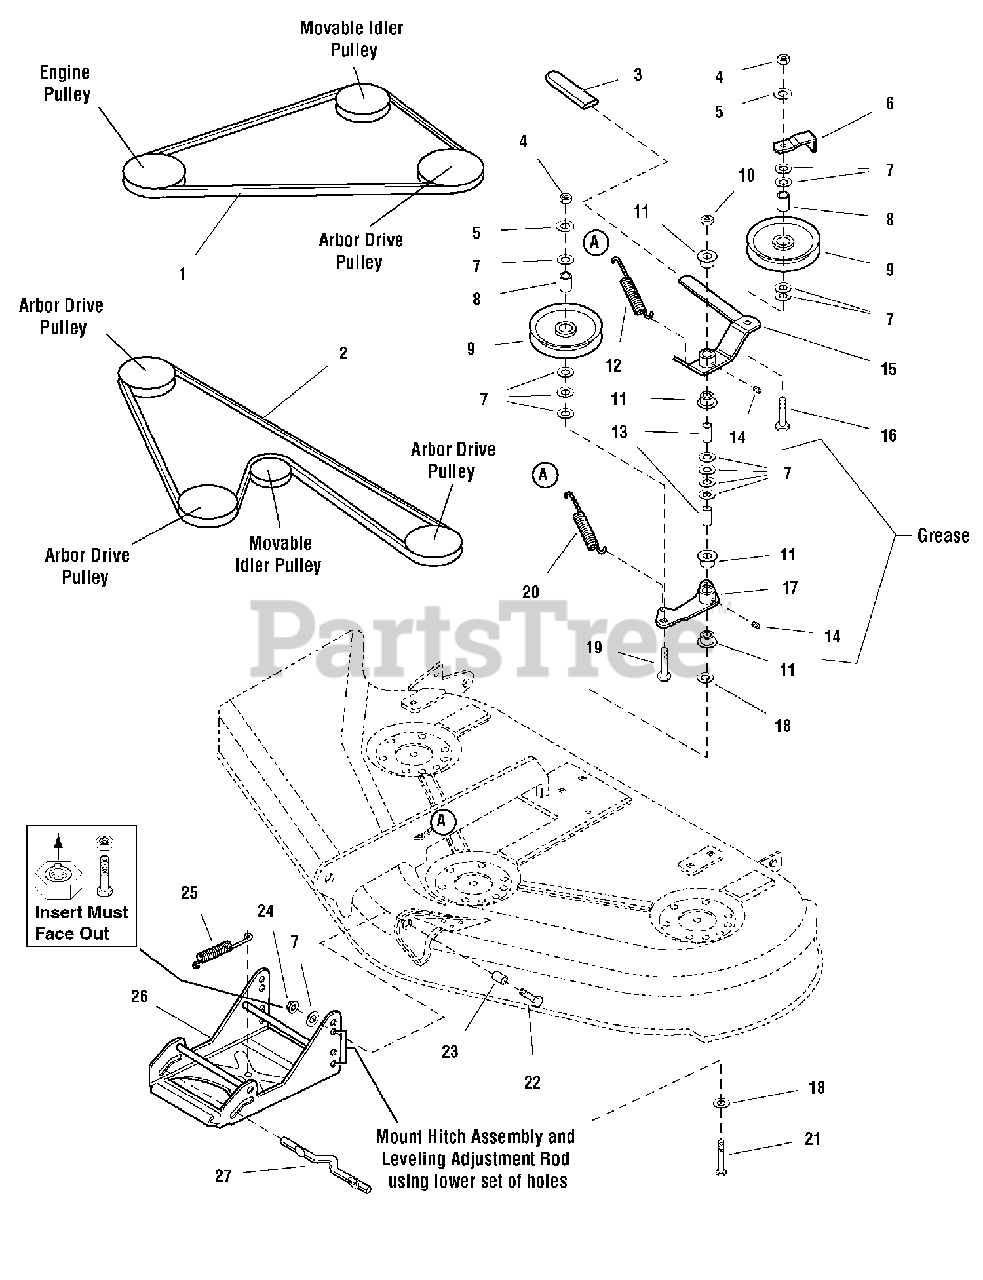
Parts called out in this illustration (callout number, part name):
1	V-BELT, Mower Drive
2	V-BELT, Arbor Drive
3	GRIP, Lever
4	NUT, Hex, 3/8-16
5	WASHER, Lock, 3/8
6	BELT STOP, Idler
7	WASHER, 3/8
8	HUB, 25/64 x 3/4 x 63/64, Powder Metal
9	PULLEY, Idler
10	NUT, Hex Flange, 3/8-16, MAC Lock Large, Black
11	BUSHING, 5/8 x 3/4 x 13/32, Powder Metal
12	SPRING
13	SPACER, 25/64 x 5/8 x 1-1/8, Case Hardened
14	GREASE FITTING
15	LEVER ASSEMBLY, Idler
16	CARRIAGE BOLT, 3/8-16 x 2
17	LEVER ASSEMBLY, Idler Arm
18	WASHER, 3/8, Black
19	CARRIAGE BOLT, 3/8-16 x 1-1/2
20	SPRING
21	CAPSCREW, Hex Head, 3/8-16 x 3-1/2
22	CAPSCREW, Hex Head, 3/8-16 x 1-3/8
23	SPACER, 3/8 x 3/4 x 1/2
24	NUT, Hex Aluminum Insert Lock, 3/8-16
25	SPRING
26	HITCH ASSEMBLY
27	ROD, Latch
